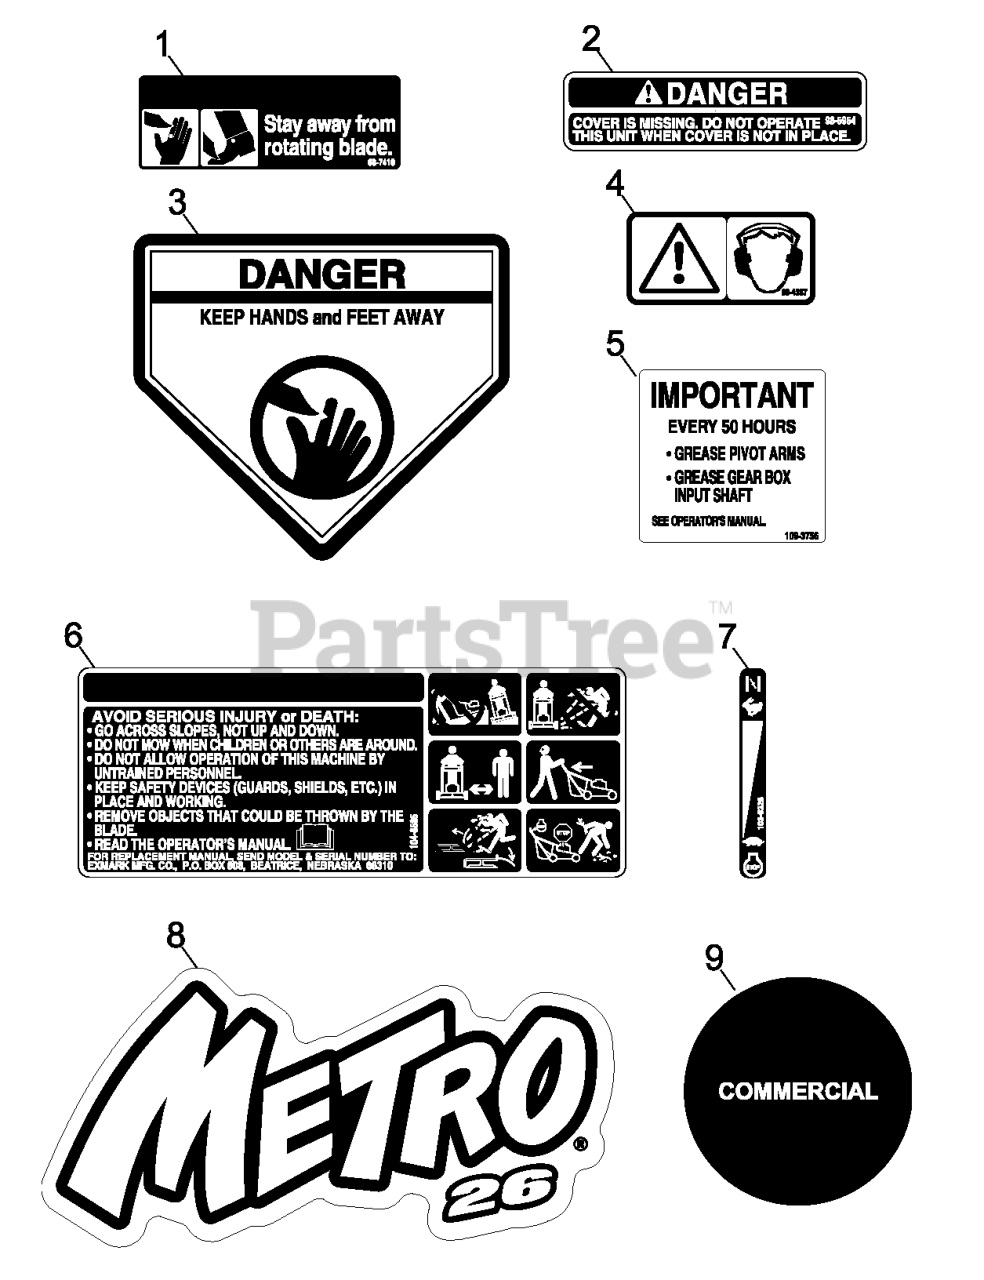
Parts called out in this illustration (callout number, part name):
1	DECAL-BLADE
2	DECAL-COVER, MISSING
3	DECAL-DANGER
4	DECAL-PROTECTION, EAR
5	DECAL,SERVICE M26
6	DECAL-WARNING
7	DECAL-THROTTLE / CHOKE
8	DECAL,METRO 26
